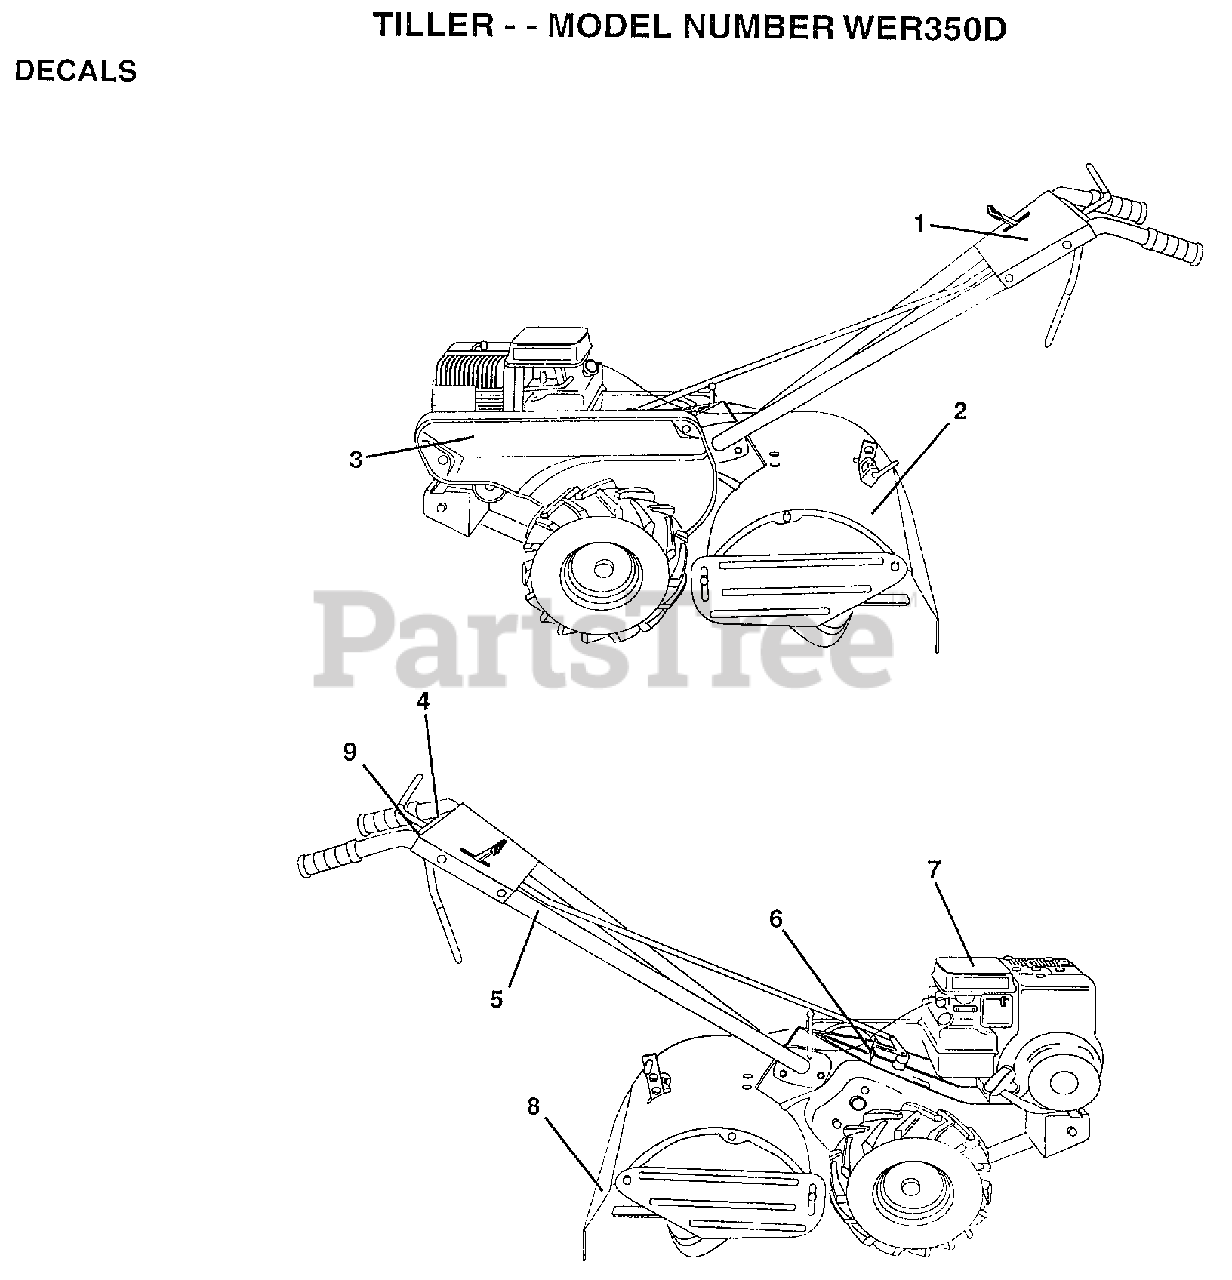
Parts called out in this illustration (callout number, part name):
1	"DECAL PANEL, CONT"
2	DECAL SHIELD TINE
3	DECAL GUARD BELT
5	DECAL TI
7	DECAL TI
9	DECAL REVERSE
